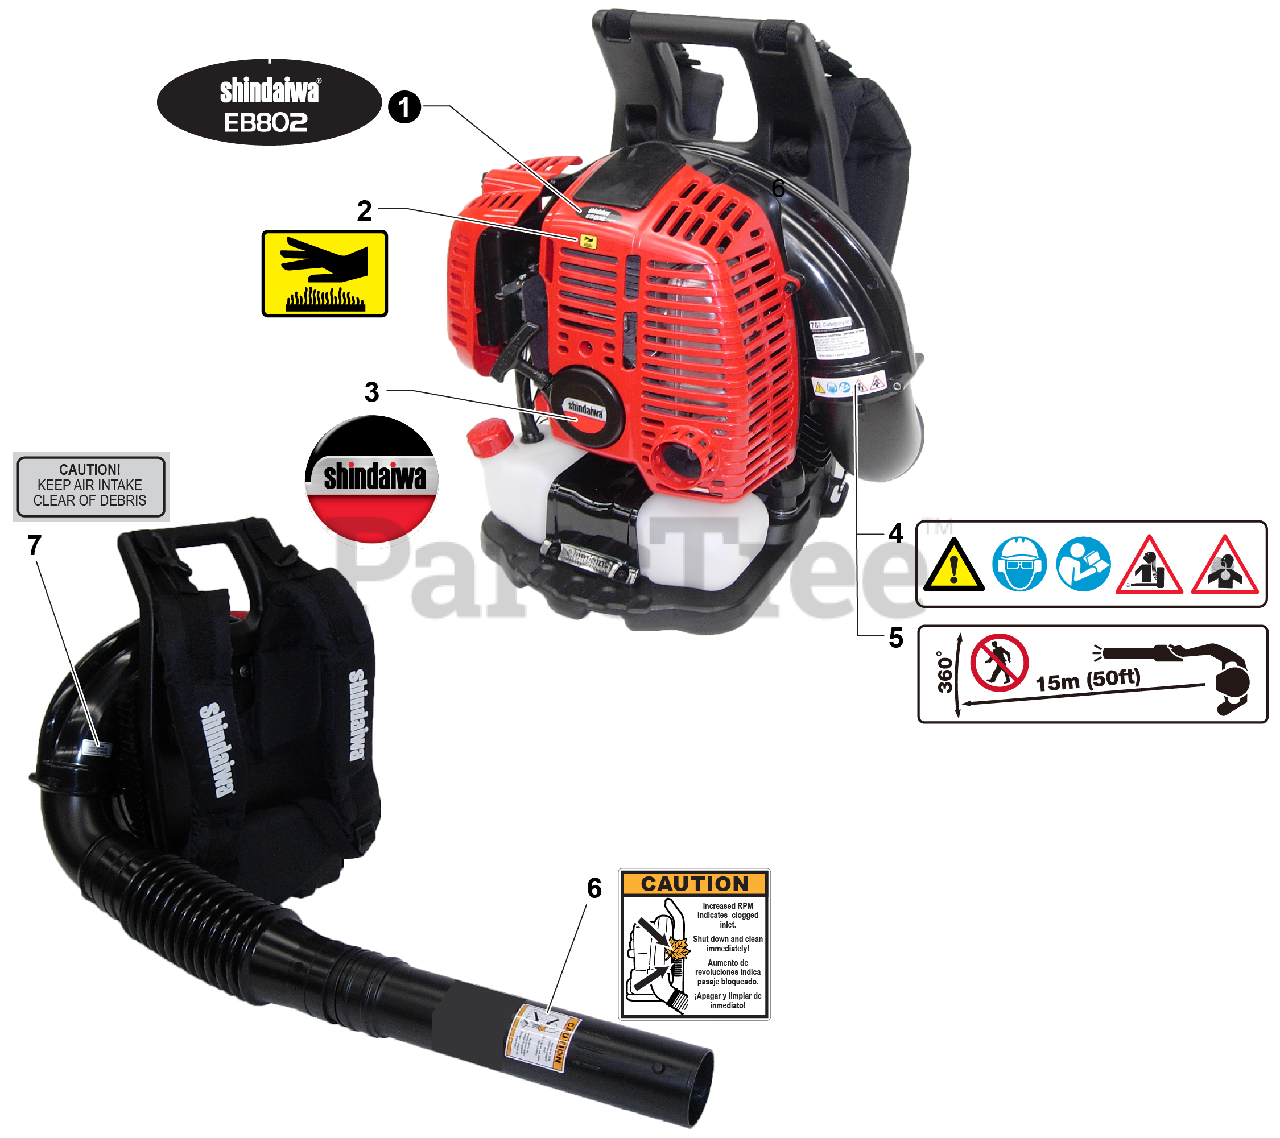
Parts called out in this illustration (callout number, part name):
1	LABEL, MODEL - EB802
2	LABEL, CAUTION - HOT
3	LABEL, RECOIL STARTER
4	LABEL, CAUTION
5	LABEL, CAUTION - BLOWER
6	LABEL, CAUTION
7	LABEL, CAUTION - AIR INTAKE
